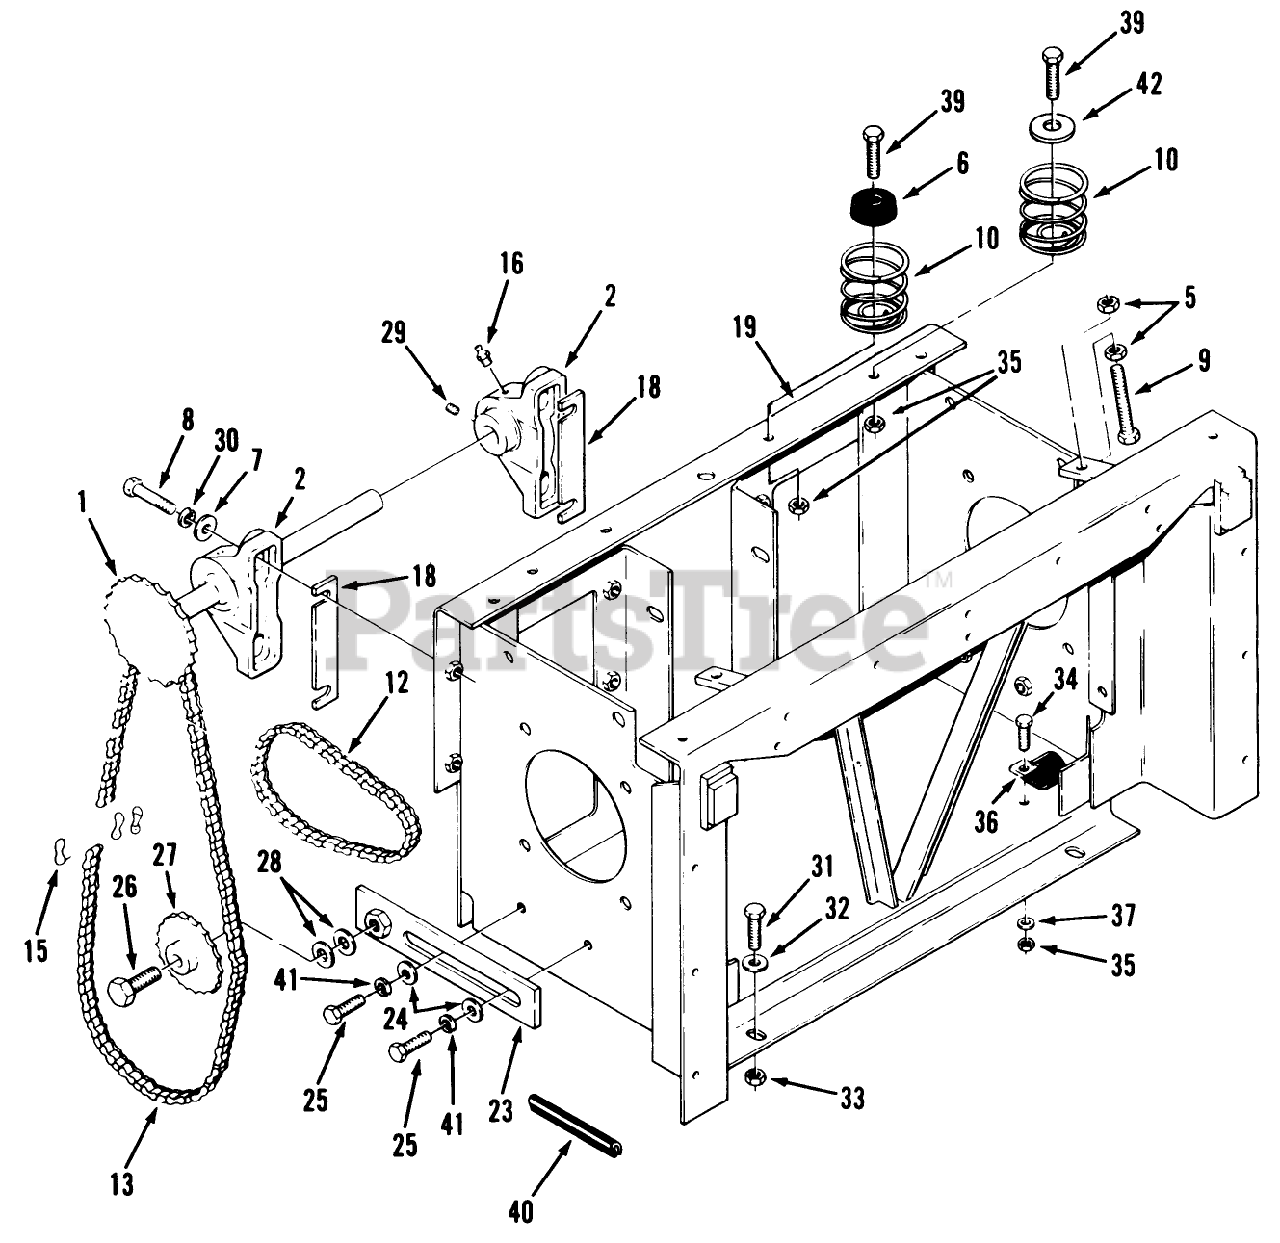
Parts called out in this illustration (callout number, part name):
1	ASSY-JACKSHAFT *PLT
6	BUMPER
10	SPRING-SEAT NYLON
18	SHIM-PILLOW BLOCK
19	WLDMT-FRAME TRANS *B
36	CLIP
37	WASHER 5/16 SAE
42	WASHER
